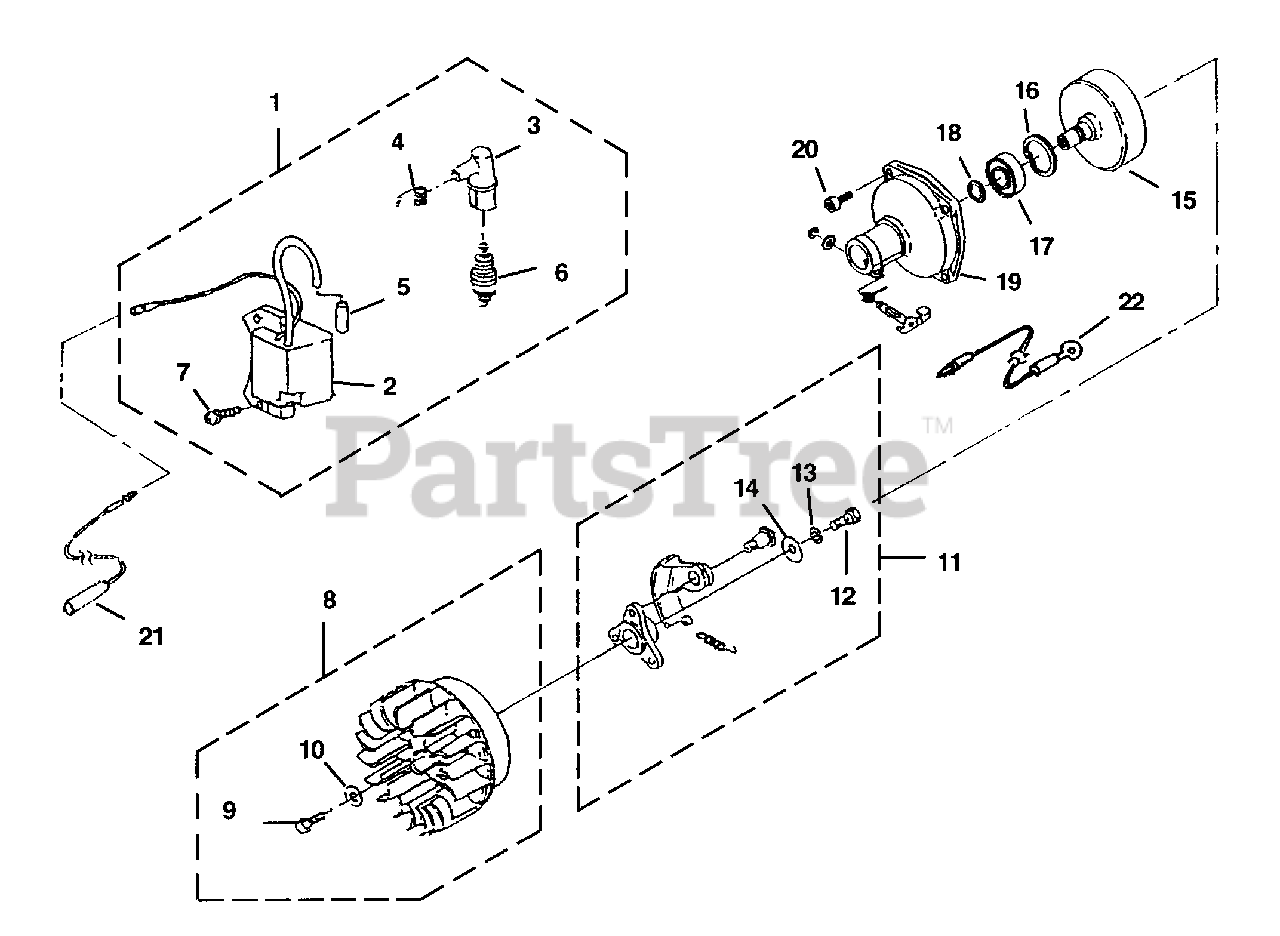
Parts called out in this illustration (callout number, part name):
1	IGNITION KIT
2	MODULE - Ignition
3	CAP - Plug
4	SPRING-Plug Cap
6	SPARK PLUG
7	SCREW-Socket Hd (M5 x 22 W)
8	ROTOR ASSEMBLY
9	BOLT
11	CLUTCH ASSEMBLY
12	BOLT
13	WASHER - Spring
15	CLUTCH DRUM
16	SNAP RING R-35
17	BALL BEARING #620ZZZ
18	SNAP RING S-15
19	CLUTCH HOUSING
20	TORX BOLT M6 X 18
